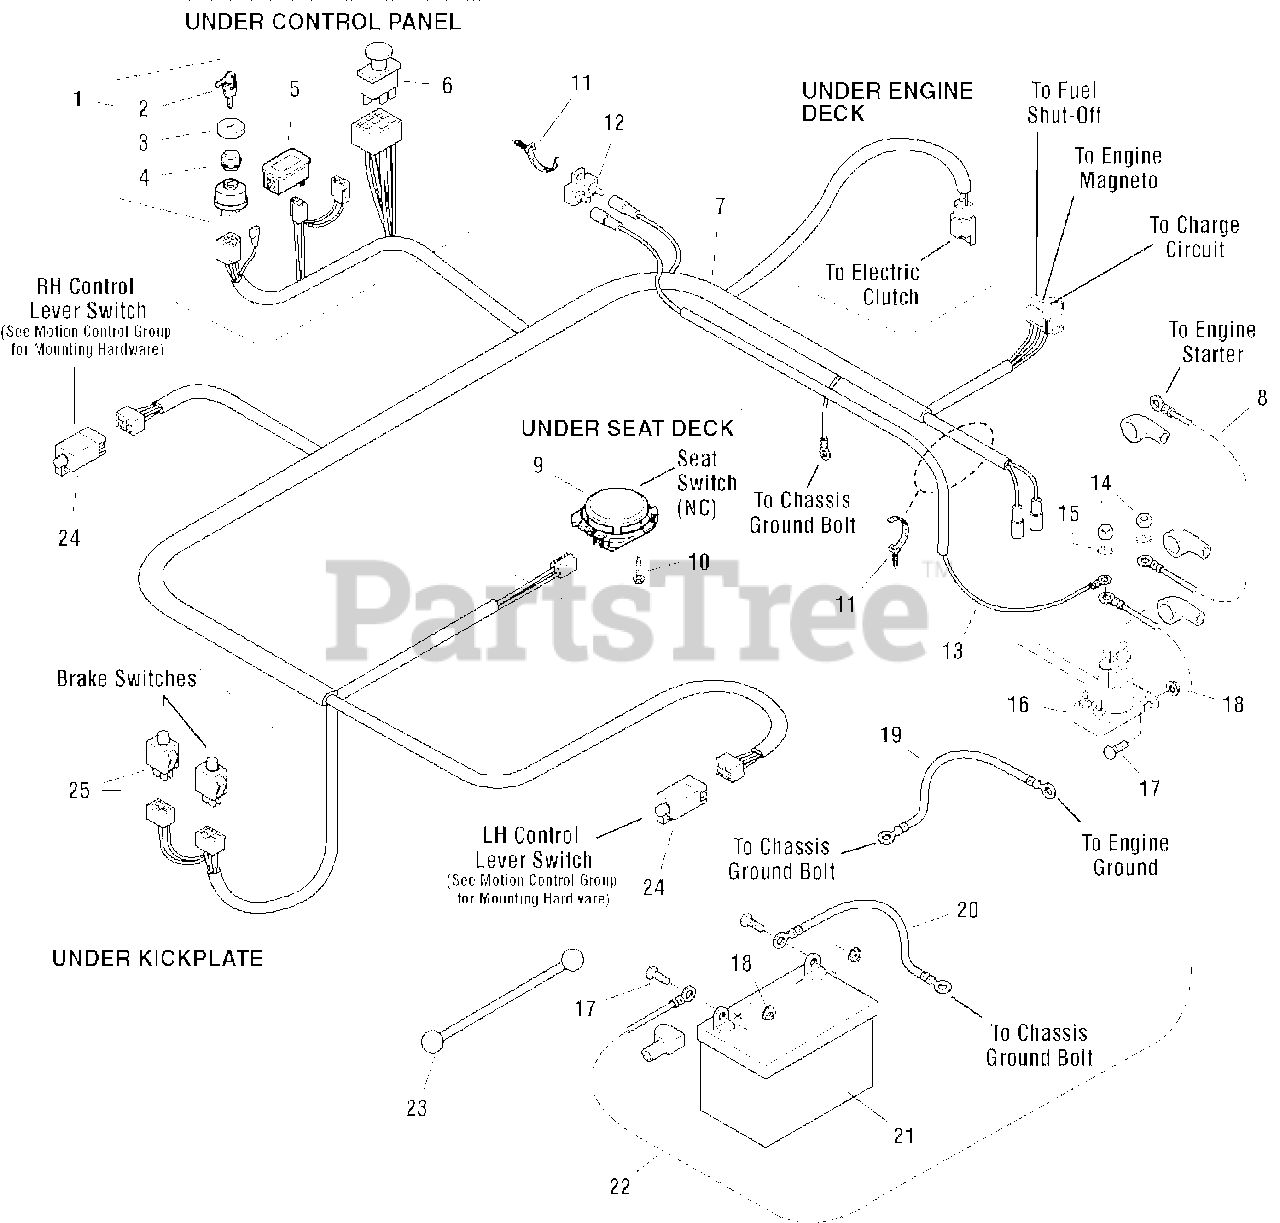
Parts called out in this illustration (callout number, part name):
1	SWITCH, IGNITION, 6 POST
2	KEY, Ignition Molded (Set of 2)
3	COVER, PLASTIC, SNAP ON
4	PLASTIC NUT
5	HOUR METER, DIGITAL (Includes Retaining Ring)
6	SWITCH, PTO
7	MAIN HARNESS ASSEMBLY
8	CABLE, #6 X 15" LONG, RING TERMINAL
9	SWITCH, SEAT, GRAY, NC
10	CAPSCREW, HEX WASHER HEAD PLASTITE, 1/4 X 1/2
11	CABLE TIE, PUSH MOUNT
12	CIRCUIT BREAKER, 20A
13	CRICUIT BREAKER WIRE ASSEMBLY
14	NUT, HEX JAM, 5/16-24
15	WASHER, LIGHT LOCK, 5/16
16	SOLENOID
17	CAPSCREW, HEX HEAD, 1/4-20 X 3/4
18	NUT, HEX SERRATED FLANGE, 1/4-20
19	CABLE, #6 X 10" LONG, RING TERMINAL
20	CABLE, #6 X 22" LONG, RING TERMINAL
21	BATTERY, 12 VOLT
22	CABLE, #6 X 30" LONG, RING TERMINAL
23	STRAP, BATTERY, 14 LONG, RUBBER
24	SWITCH, PLUNGER, NO/NC
25	SWITCH, PLUNGER, NO/NC, SNAP IN
